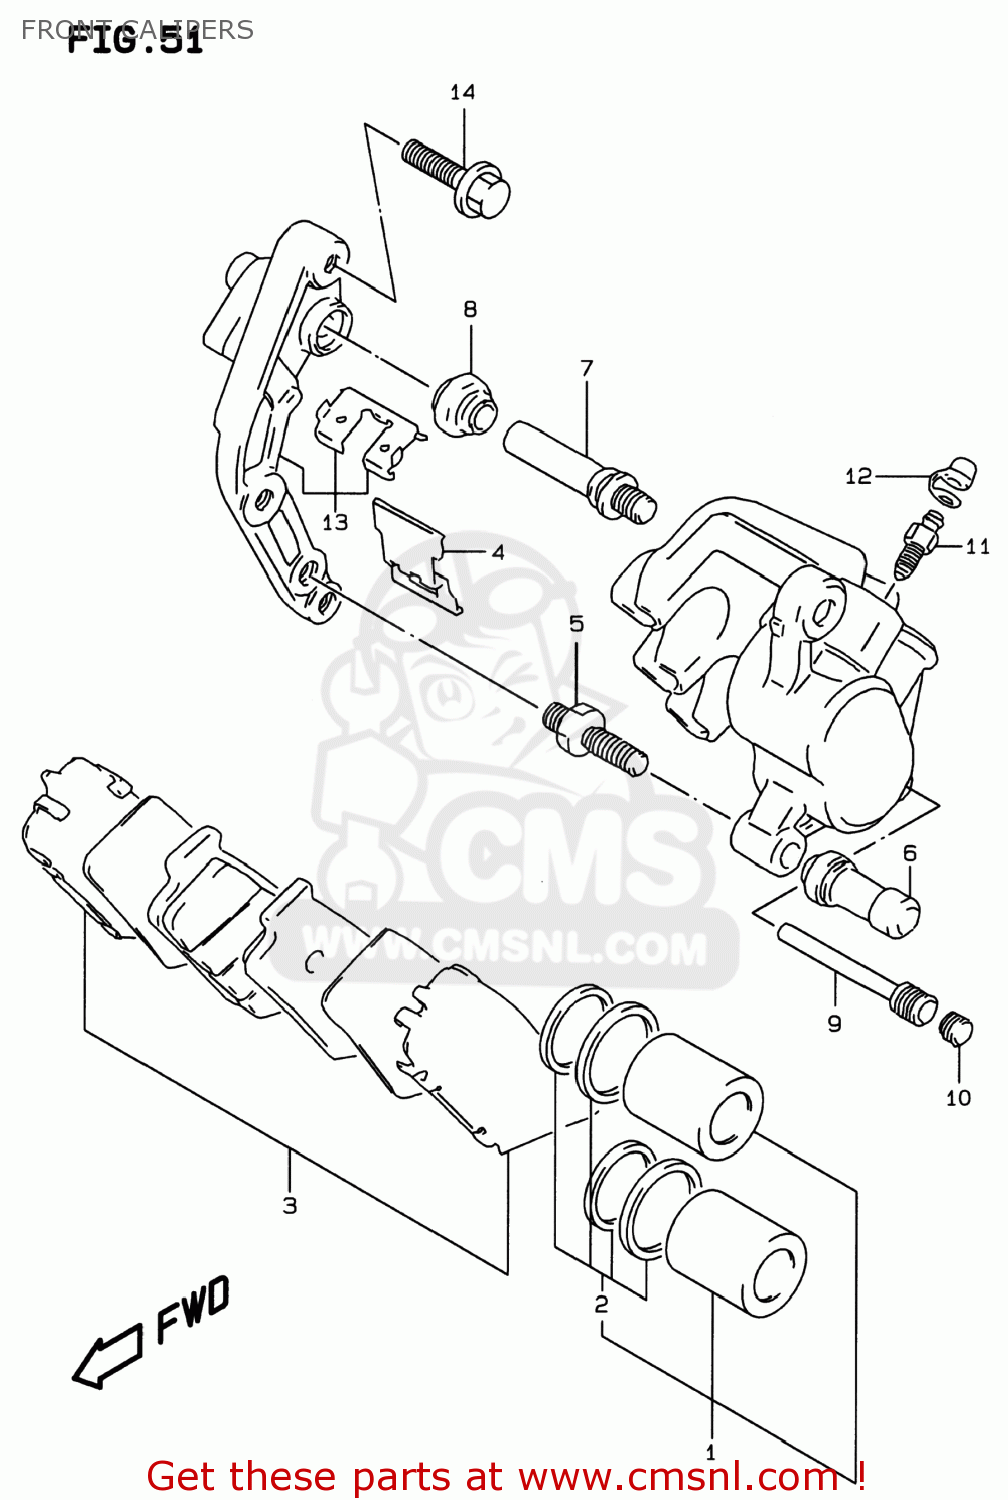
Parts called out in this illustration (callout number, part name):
1	PISTON SET
2	SEAL SET,PISTON
3	PAD & RETAINER SET
4	SPRING,PAD
5	BOLT
6	BOOT
7	PIN
8	BOOT
9	PIN,HANGER
10	PLUG,PIN
11	BLEEDER
12	CAP,BLEEDER
13	BRACKET,R
14	BOLT(8X30)
